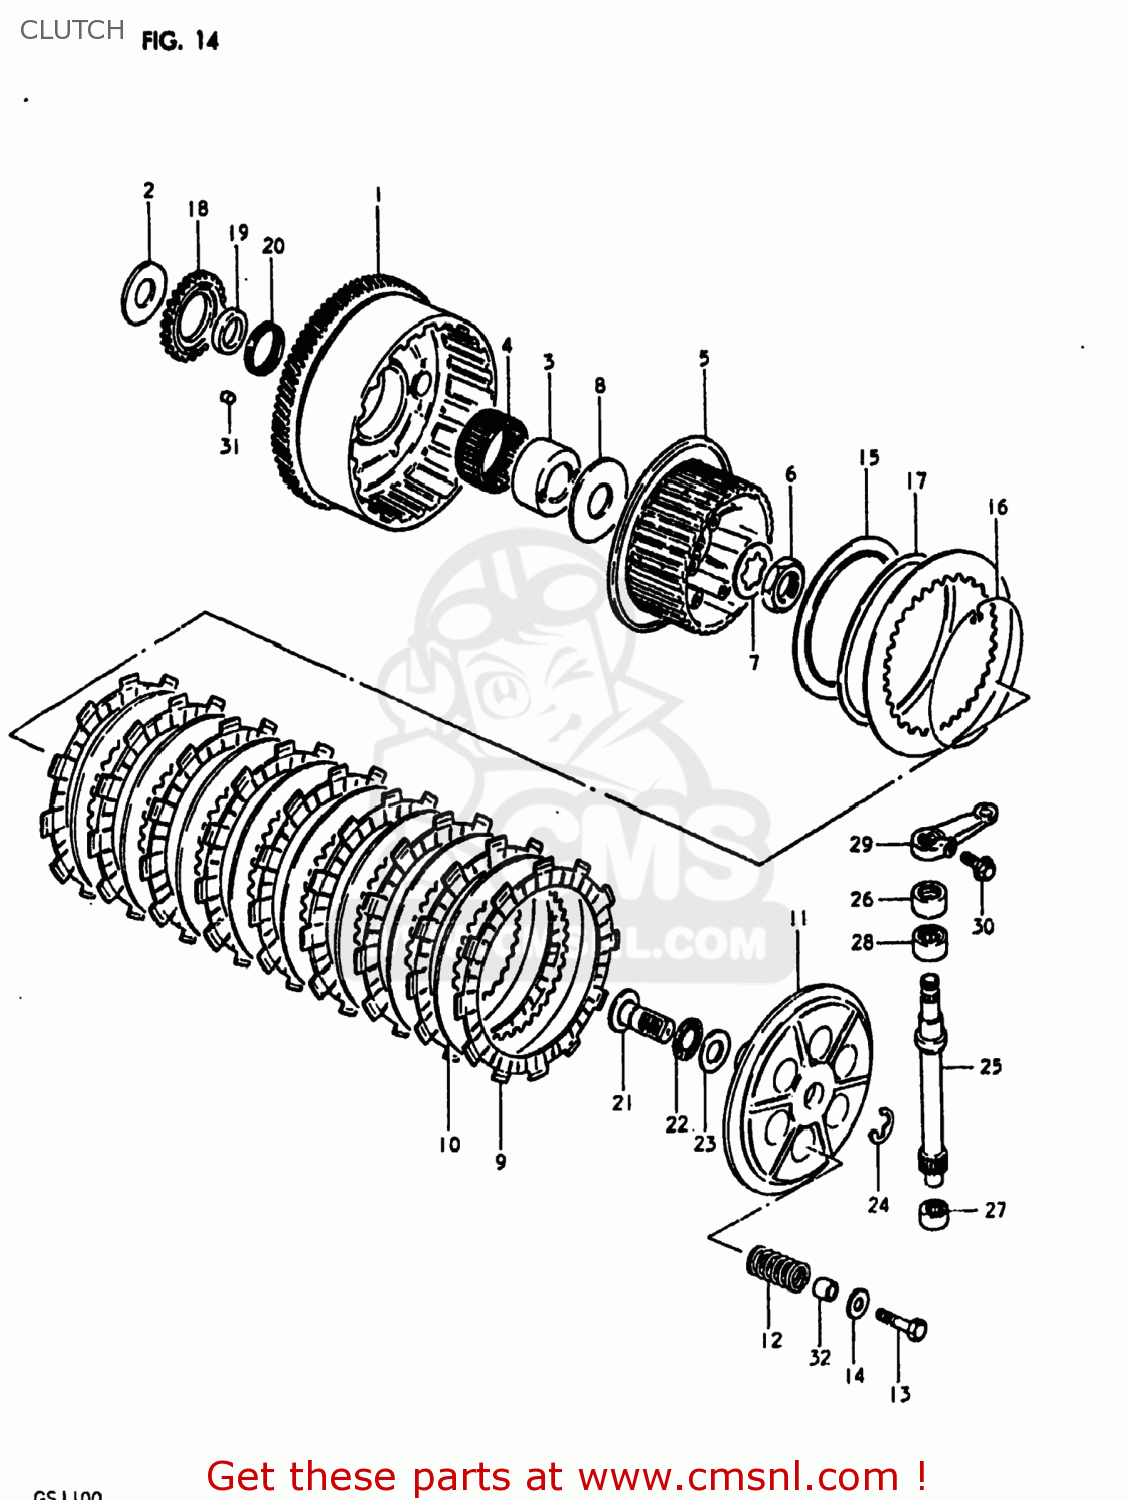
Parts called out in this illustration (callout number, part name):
1	GEAR ASSEMBLY,PRIMARY DRIVE
2	WASHER
3	SPACER
4	BEARING
5	HUB,CLUTCH SLEEVE
6	NUT
7	WASHER,LOCK
8	WASHER(25X66X3.5)
9	PLATE,CLUTCH DRIVE (MCA)
10	PLATE,CLUTCH DRIVEN (NAS)
11	DISC,CLUTCH PRESSURE
12	SPRING
13	BOLT
14	WASHER
15	SEAT,WAVE WASHER
16	RING,STOPPER
17	WASHER
18	GEAR,OIL PUMP DRIVE
19	SPACER,OIL PUMP DRIVE GEAR
20	BEARING(36X40X10)
21	RACK,CLUTCH RELEASE
22	BEARING(15X28X2)
23	WASHER
24	WASHER
25	PINION,CLUTCH RELEASE
26	OIL SEAL
27	BEARING(12X19X12)
28	BEARING(15X22X12)
29	ARM,CLUTCH RELEASE
30	BOLT
31	CUSHION,PRIMARY DRIVEN GEAR
32	SPACER
